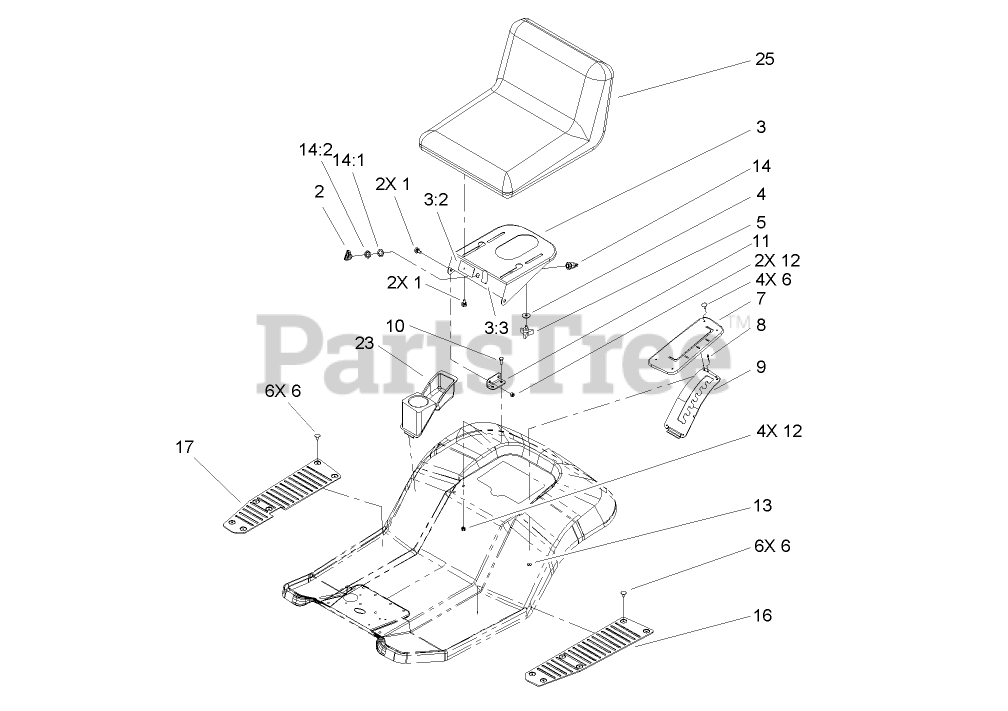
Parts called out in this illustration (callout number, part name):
1	BOLT-SHOULDER
2	KEY-IGNITION
3	SEAT SUPPORT ASM
3:2	DECAL-DANGER
3:3	DECAL-SWITCH, NMIR
4	WASHER-PIVOT
6	FASTENER-PANEL
7	COVER-HOC
8	RIVET-BLIND
9	GATE-HOC
10	SCREW-HH
11	BRACKET-PIVOT, SEAT
12	NUT-LOCK, NI
13	WASHER-PLAIN
14	STARTER SWITCH ASM
14:1	WASHER-LOCK
14:2	NUT-HH
16	MAT-FOOT, LH
17	MAT-FOOT, RH
23	TRAY-FENDER
